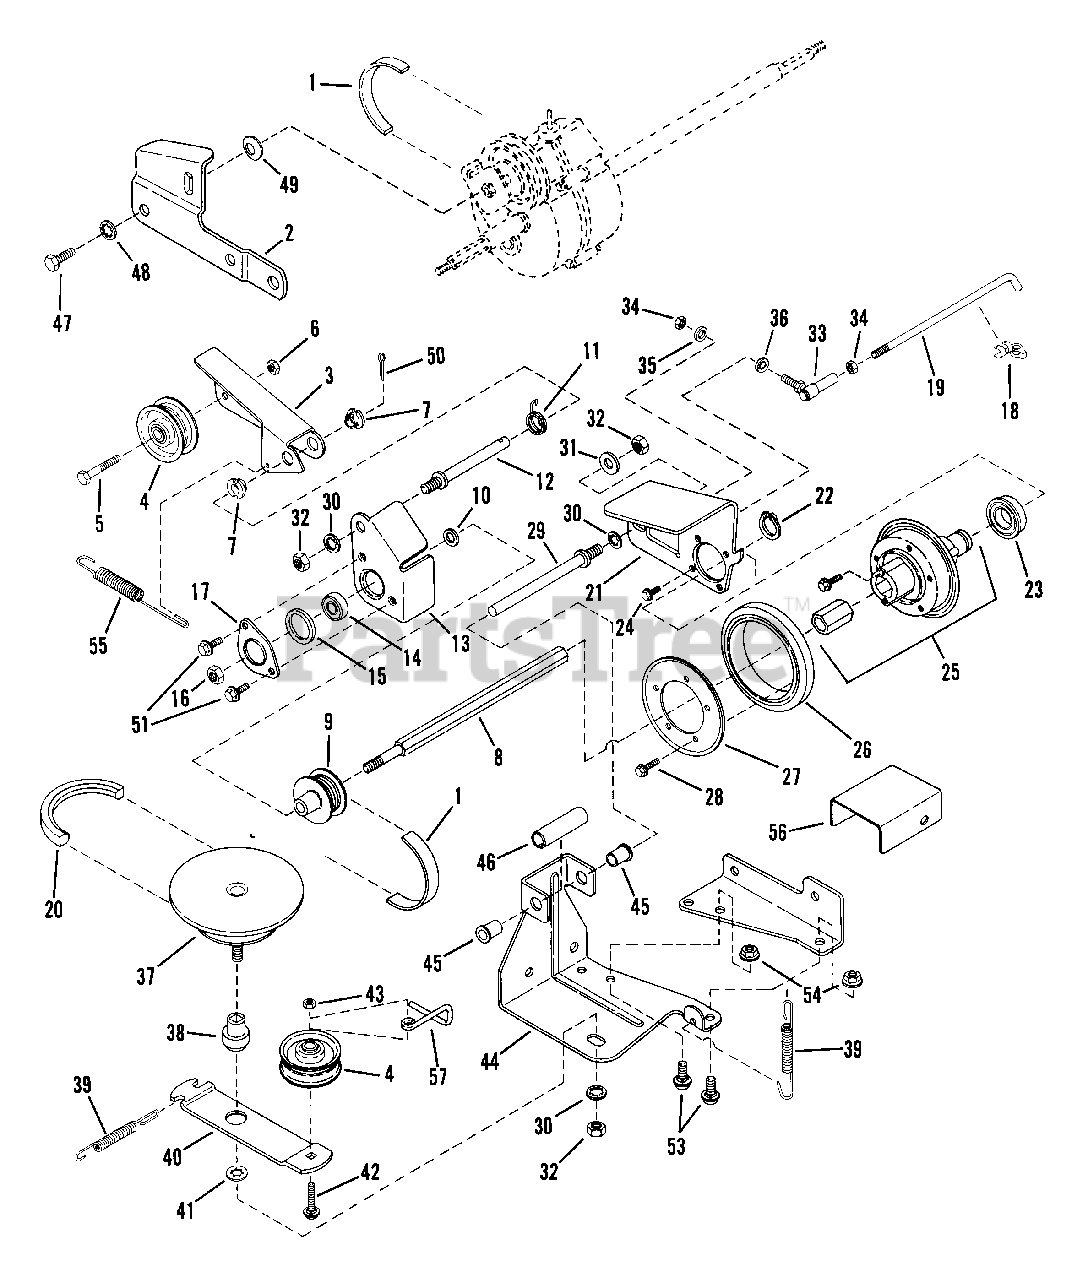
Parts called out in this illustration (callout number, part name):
1	BELT, Poly-Vee
2	LINK, Differential
3	ARM, Clutch Idler
4	PULLEY, Idler
5	CAPSCREW, 1/4-28 x 1-3/8" Hex Head
6	NUT, 1/4-28 Hex Lock
7	BUSHING, 3/8 I.D. Nylon
8	HEX-SHAFT
9	PULLEY
10	WASHER
11	SPRING, Torsion
12	STUD
13	HOLDER, Bearing (Inner Half)
14	BEARING, Ball
15	O-RING
16	NUT, 3/8 Hex Center Lock
17	HOLDER, Bearing (Outer Half)
18	CLIP, 1/4 Right Arc (Transfer Rod)
19	LINK, Transfer
20	BELT, Engine Drive
21	PLATE, Thrust
22	RING, Retaining
23	BEARING, Ball
24	SCREW, #10-32 x 1/4" Self-Tapping Machine
25	ASSEMBLY, Hub
26	DRIVEN-RING
27	PLATE, Ring Retaining
28	SCREW, #10-24 x 1/2" Hex Washer Self-Tap (Torx)
29	GUIDE, Thrust Plate
30	WASHER, 3/8 Internal Tooth Lock
31	WASHER, 3/8" Flat
32	NUT, 3/8-24 Hex
33	JOINT, Ball
34	NUT, 1/4-28 Hex
35	WASHER, 1/4 Flat
36	WASHER, 1/4 Internal Tooth Lock
37	ASSEMBLY, Drive-Disc
38	BUSHING
39	SPRING (Wheel Drive & Idler)
40	ARM, Idler
41	RETAINER, 3/8 Bolt
42	BOLT, 1/4-20 x 1-1/4" Carriage
43	NUT, 1/4-20 Hex Center Lock
44	BRACKET, Deck
45	BUSHING, Flange
46	SPACER
47	SCREW, 5/16-18 x 1/2" Hex Head Cap
48	WASHER, 5/16 Internal Tooth Lock
49	WASHER, Spring
50	COTTER-PIN, 3/32 x 1/2"
51	SCREW, 1/4-20 x 1/2" Self-Tapping
53	BOLT, 5/16-18 x 5/8" Short Neck Carriage
54	NUT, 5/16-18 Hex Flange Lock
55	SPRING, Clutch
56	SHIELD, Hex Shaft
57	SCRAPPER, Drive Pulley
